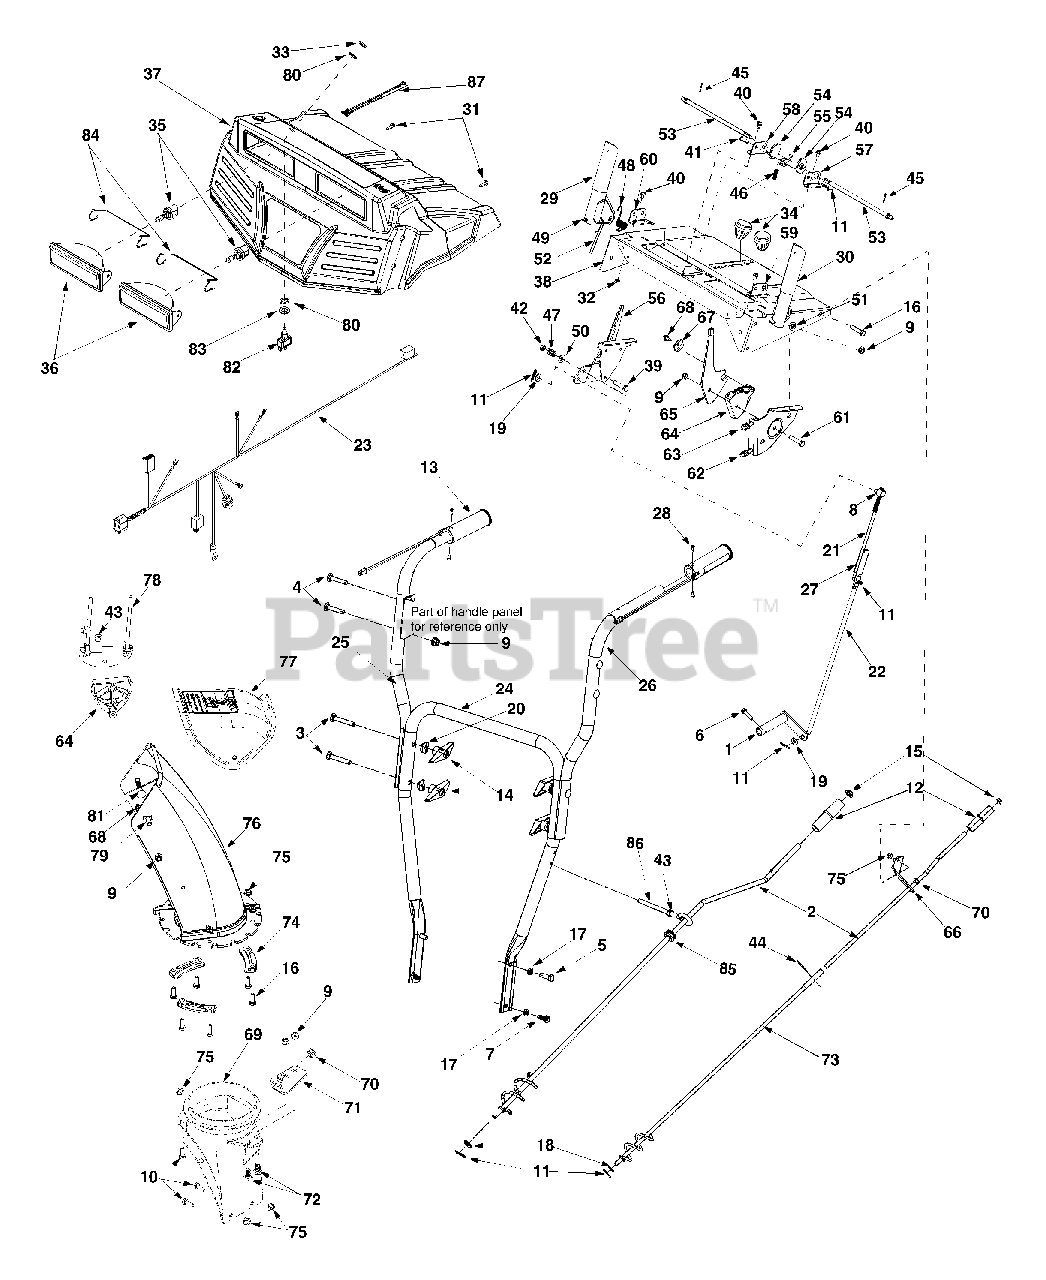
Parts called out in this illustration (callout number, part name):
3	Carriage Screw 5/16-18 x 2.25
4	Carriage Bolt 5/16-18 x 1.75
5	Hex Bolt 5/16-18 x 1.0
6	TT Screw 1/4-20 x 1.0
7	Hex Bolt 5/16-18 x 0.75
8	Ferrule
9	Flange Lock Nut
10	Carriage Screw, 1/4-20 x.75
11	Hairpin Clip
12	Chute Directional Control Knob
13	Heated Grip
14	Handle Knob Assembly
16	Hex Screw, 1/4-20 x 1.00
17	Lock Washer
18	Flat Washer
19	Flat Washer
20	Saddle Washer
21	Upper Shift Rod
22	Lower Shift Rod
23	Heated Grips Harness Ass'y
28	Screw, #10-16 x.625
29	Handle Engagement Assembly RH
30	Handle Engagement Assembly LH
31	B Screw #10-16 x 0.625
32	Hex Sems Nut 1/4-20
33	Jam Nut, 15/32-32
34	Shift Knob
35	Halogen Lamp, 50W, 12V
36	Lamp Housing
37	Handle Panel
39	Hex Bolt 3/8-24 x 1.5
40	TT Screw 1/4-20 x 0.5
41	Clevis Pin
42	Jam Lock Nut 3/8-24
43	Hex Nut, 5/16-18
44	Click Pin
45	Cotter Pin
46	Compression Spring
47	Compression Spring
48	Torsion Spring
49	Rubber Bumper
50	Bell Washer
51	Flat Washer
52	Drive Cable Z- Fitting
54	Handle Lock Cam
55	Handle Lock Pawl
61	Hex Bolt 5/16-18 x 1.5
62	Chute Deflector Cable w/Clip
63	Chute Deflector Control Cable
64	Chute Cable Guide
67	Special Washer
68	Hi-Lo Screw 1/4-15 x 0.75
69	Chute Adapter
70	Plastic Bushing
72	Carriage Bolt 5/16-18 x 0.75
75	Flange Lock Nut 1/4-20
76	Lower Chute
77	Upper Chute
79	Carriage Bolt 5/16-18 x 1.0
80	Toggle Switch Lock Ring
81	Carriage bolt 5/16-18 x 1.5
82	Single Throw Toggle Switch
83	Flat Washer
84	Headlight Retainer
85	Rubber Grommet
86	Eye Bolt
87	Light Harness
